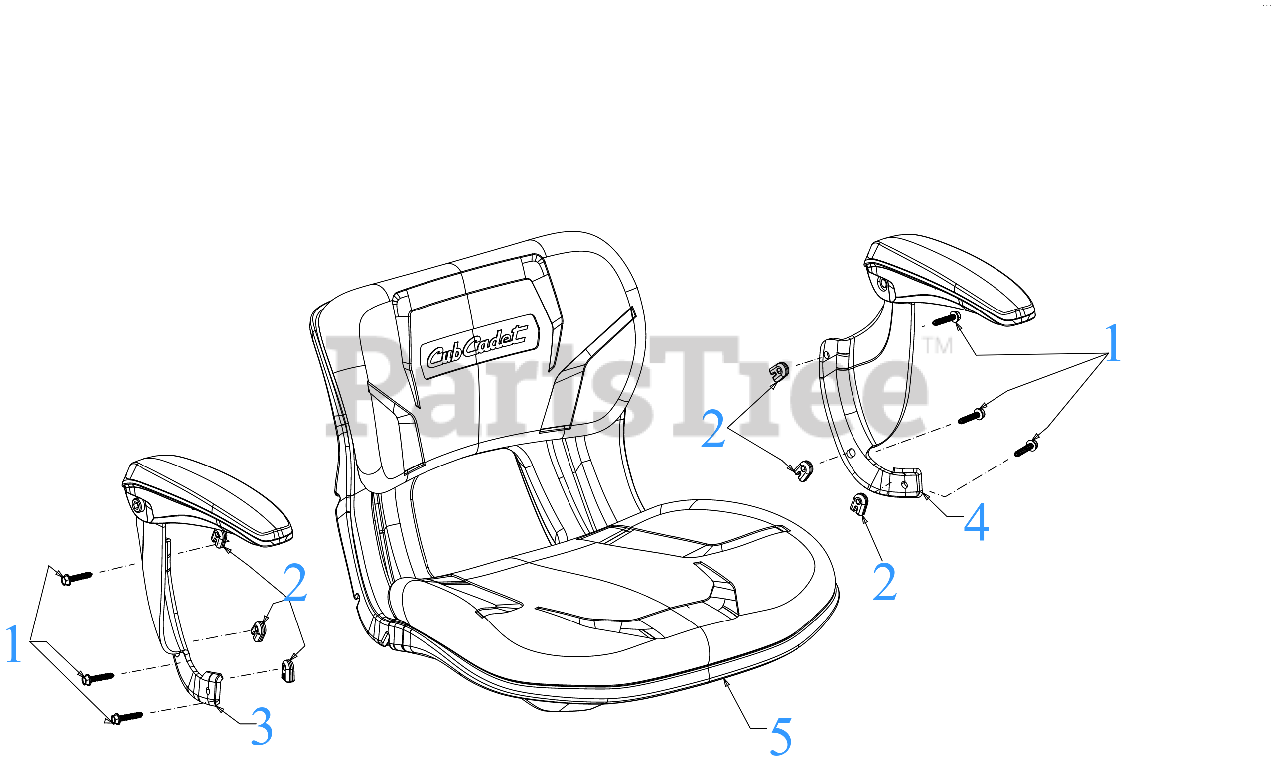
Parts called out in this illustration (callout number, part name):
1	SCREW 1/4-14X 1.25
2	ARMREST NUT
3	HIGH BACK SEAT ARM (RH)
4	HIGH BACK SEAT ARM (LH)
5	HIGH BACK SEAT
